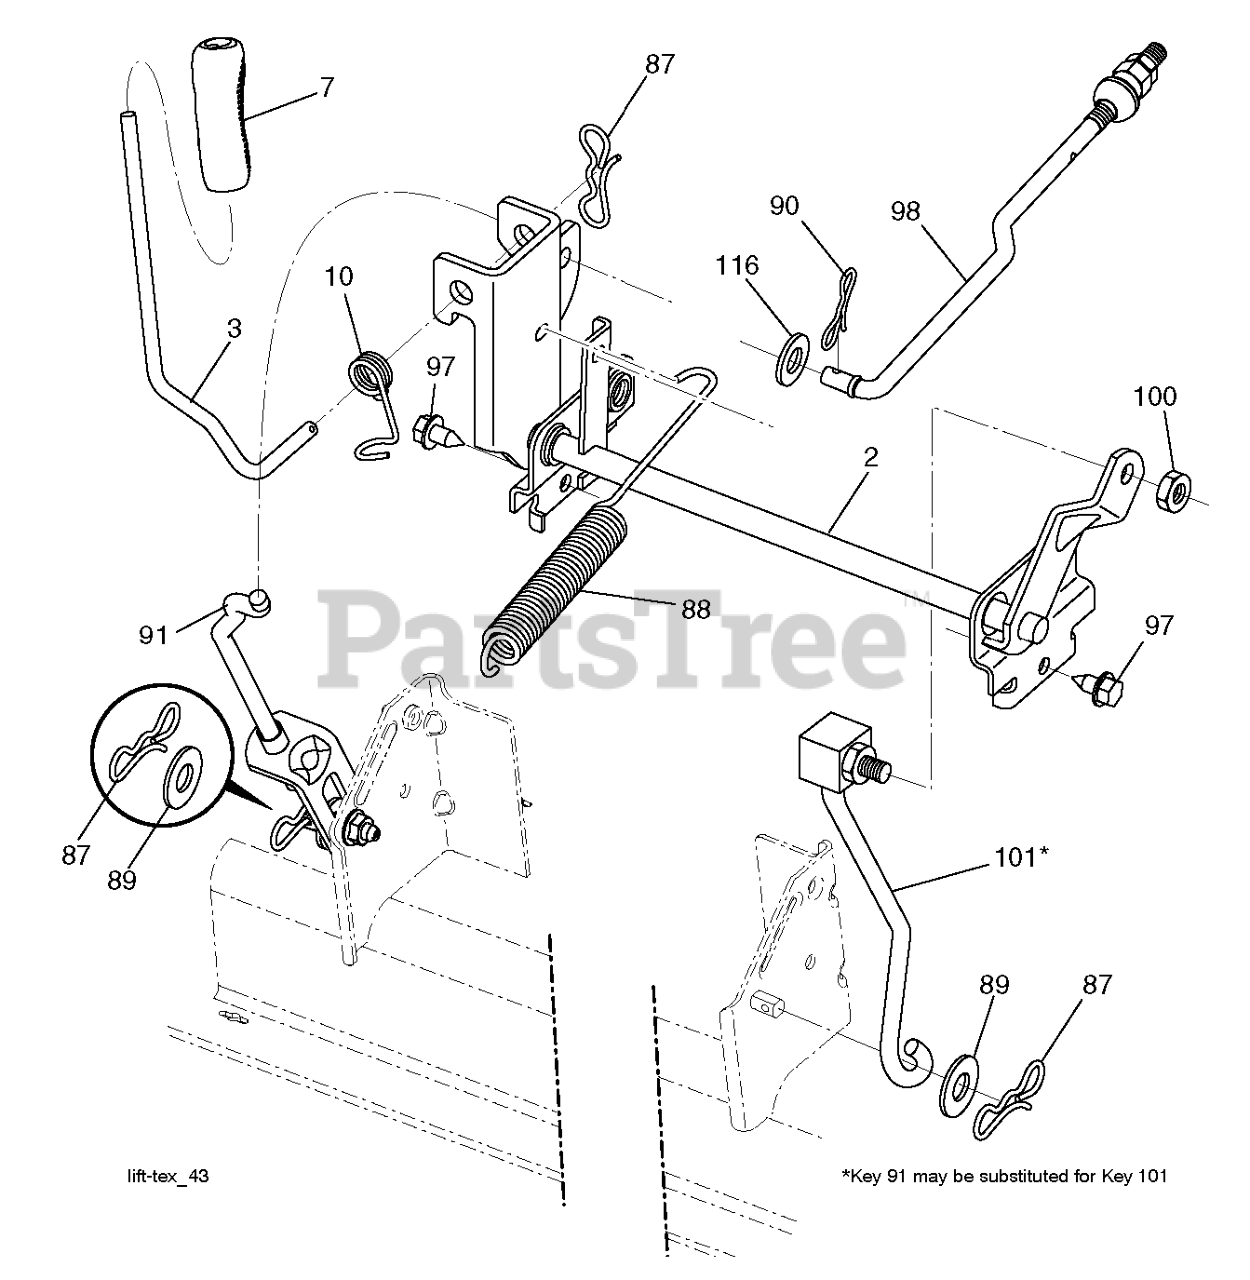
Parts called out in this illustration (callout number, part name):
2	SHAFT.ASM.CROSS.LIFT
3	LEVER.LIFT.HANDLE.LT
7	GRIP.HANDLE.LIFT.PVC.BLACK
10	SPRING.TORSION.LIFT.HANDLE
87	PIN.COTTER.7/16.BOW TI.
88	SPRING.LIFT.ASSIST
89	WASHER.CLEAR.ZINC
90	PIN.COTTER.5/16.BOW TI
91	LINK.ASM.LIFT.REAR
97	SCREW, 3/8-16X3/4
98	LINK.ASM.SUSP.FRONT.MW
100	LOCKNUT
101	LINK.ASM.LIFT.FIXE.38/42/46"
116	WASHER
116	WASHER.CLEAR.ZINC
